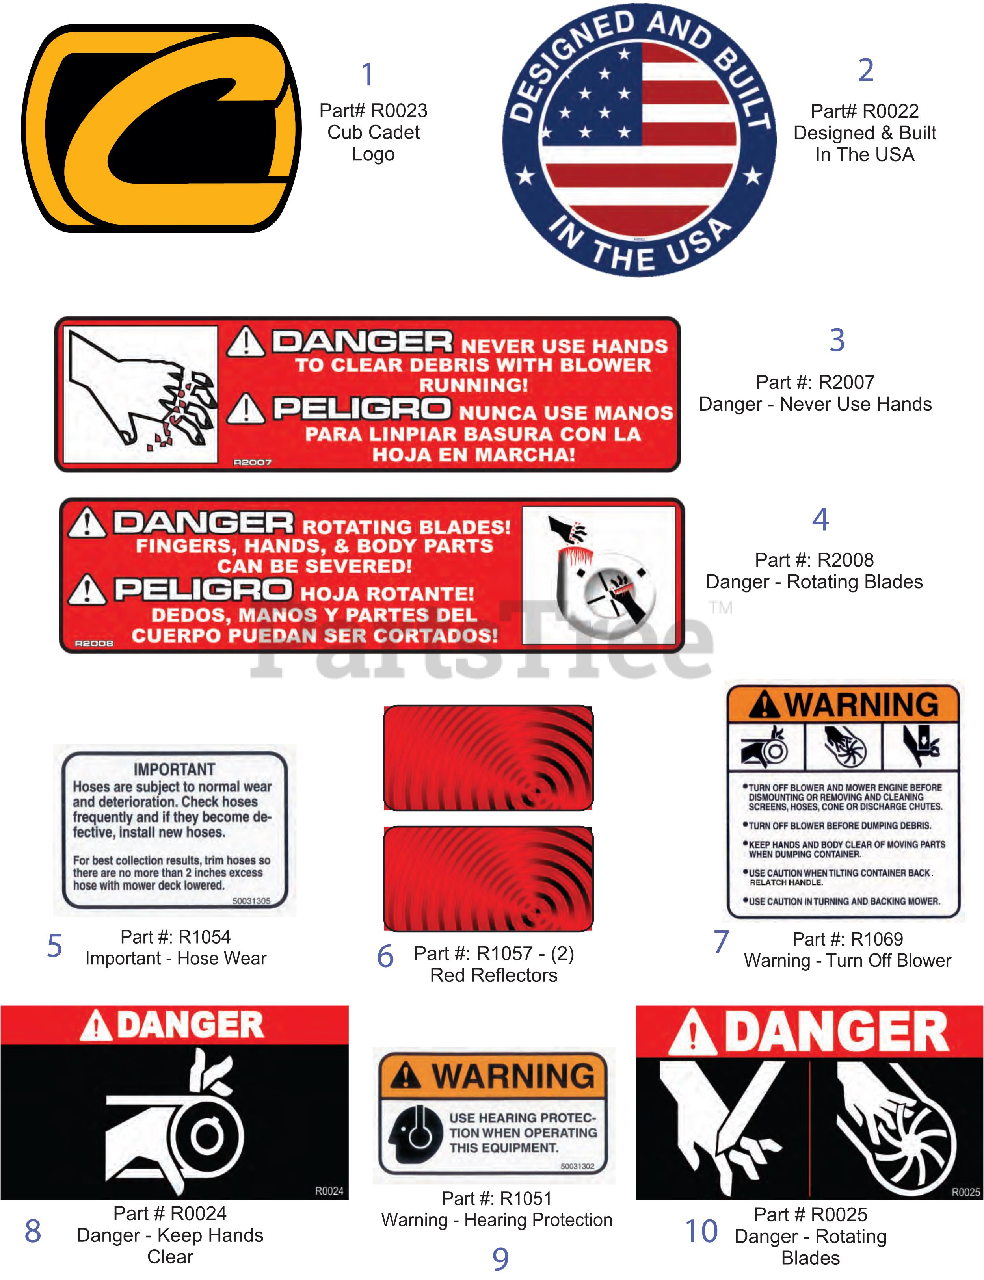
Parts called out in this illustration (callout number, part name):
1	Cub Cadet Logo Label
2	Built In Usa Label
3	Label-Never Use Ha
4	Label-Rotating Bla
5	Decal-Tube Wear
6	Label-2 X 4 Red Re
7	Label-Warning
8	Danger - Hands Clear Label
9	Decal-Warning
10	Danger - Rotaing Blades Label
